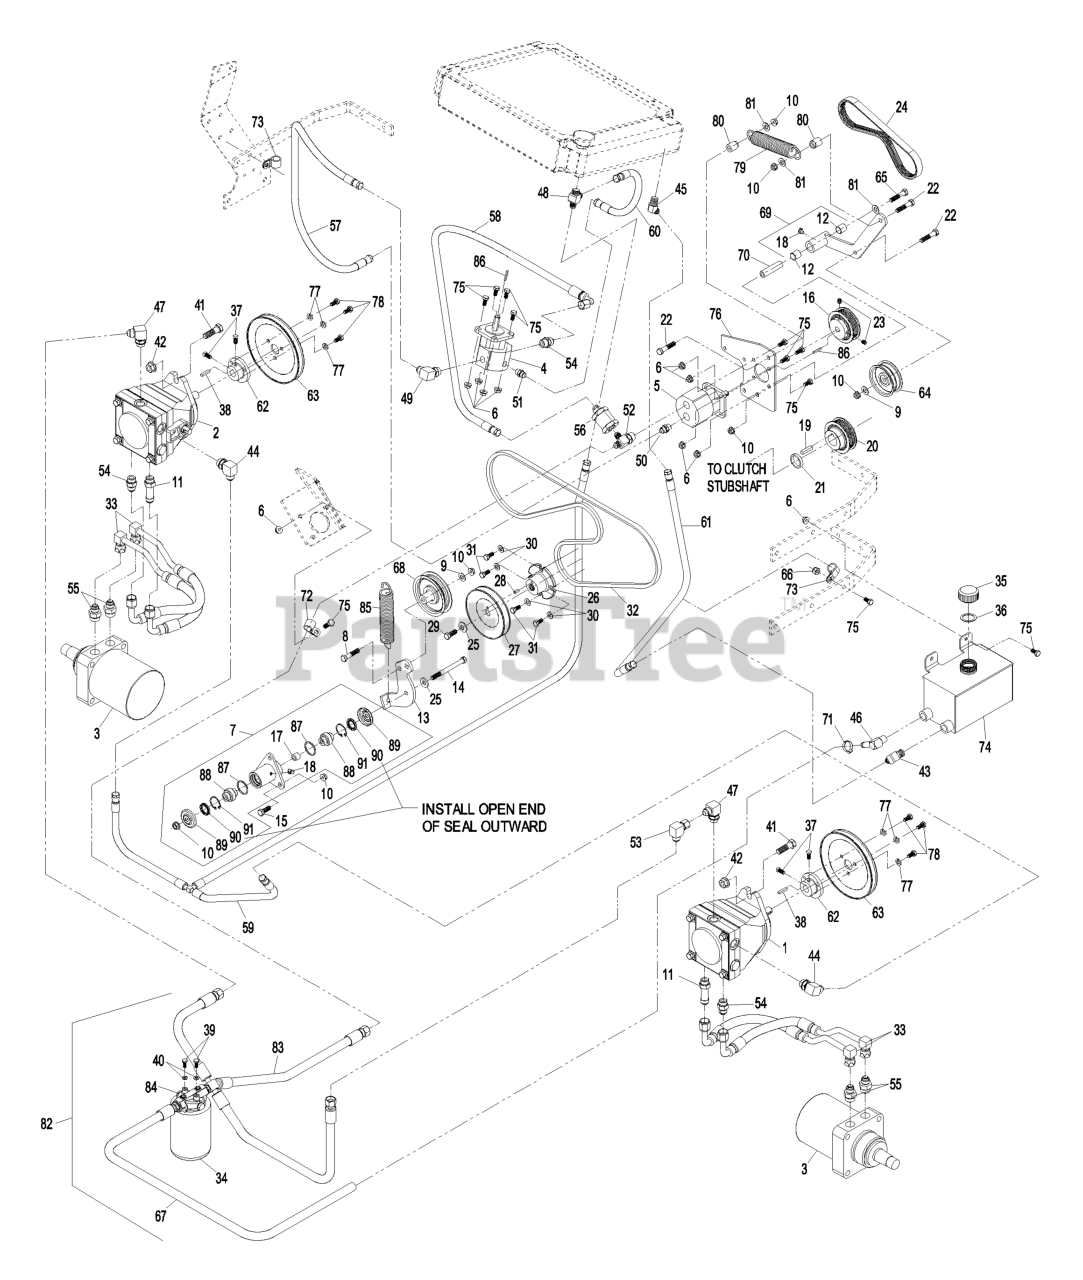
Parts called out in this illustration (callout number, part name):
1	PUMP-HYDRO, LH
2	PUMP-HYDRO, RH
4	MOTOR-FAN, COOLING
5	PUMP-FAN, COOLING
7	KIT,'04 XP PUMP IDLER
8	BOLT-CARR
9	WASHER-FLAT
10	NUT-HHF, WHIZ
11	ADAPTER-STR, LONG
12	SLEEVE-BEARING
13	ARM-TIGHTENER, PUMP
14	SCREW-HH
15	SCREW-HH
16	SHEAVE-5 RIB
17	BUSHING-LEVER, LIFT
18	FITTING-GREASE, 90 DEG
19	KEY-SQUARE
20	SHEAVE-5 RIB
21	SPACER-PUMP DRIVE, FAN
22	SCREW-HH
23	SCREW-SET, HSH
24	BELT,POLY-V K 25.38"
25	WASHER-BELLEVILLE
26	HUB-DRIVE, PUMP
27	SHEAVE-ENGINE
28	PIN-ROLL
29	SCREW-HH
30	WASHER-PLAIN
31	SCREW-HH
32	BELT,WRAPPED A-71.26
33	HYD HOSE ASM
34	FILTER,XP HYD 25 MICRON
36	GASKET-CAP, TANK
37	SCREW-SET
39	SCREW-HH
40	WASHER-LOCK
41	SCREW-HH
42	NUT-HHF
43	FITTING-ELBOW, 90 DEG
44	FITTING-ELBOW, 90 DEG
45	FITTING-45 DEG
46	FITTING-90 DEG
47	FITTING-90 DEG
48	FITTING-TEE
49	FITTING-90 DEG
50	FITTING-STRAIGHT
51	FITTING-STRAIGHT
52	FITTING-TEE
53	FITTING-90 DEG
54	FITTING-STRAIGHT
55	FITTING-STRAIGHT
56	FILTER-IN LINE, 50 MICRON
57	AUXILLARY PUMP HOSE ASM
58	HOSE-PRESSURE, HIGH
59	CASE DRAIN HOSE ASM
60	FAN CASE DRAIN HOSE ASM
61	TANK RETURN HOSE ASM
62	HUB-PUMP
63	SHEAVE-PUMP
64	SHEAVE-IDLER
65	SCREW-CARR
66	NUT-LOCK, NI
67	FILTER INLET HOSE ASM
68	IDLER-PUMP
69	ASM,IDLER ARM W/DECALS
70	BUSHING-PIVOT, IDLER
72	CLIP-LOOM
73	CLIP-LOOM
74	KIT,HYD TANK W/DECALS
75	SCREW-HH
76	PLATE-MATING, FAN PUMP
77	WASHER-LOCK
78	SCREW-HH
79	SPRING-EXTENSION
80	SPACER-SPRING, FAN PUMP
81	WASHER-FLAT
82	CHARGE HOSE ASM
83	PUMP INLET HOSE ASM
84	HEAD-FILTER
85	SPRING-EXTENSION
86	KEY-SQUARE
88	BEARING-SPHERICAL
89	GUARD-TOP
90	SEAL-LIP, SINGLE
91	RING-SNAP
